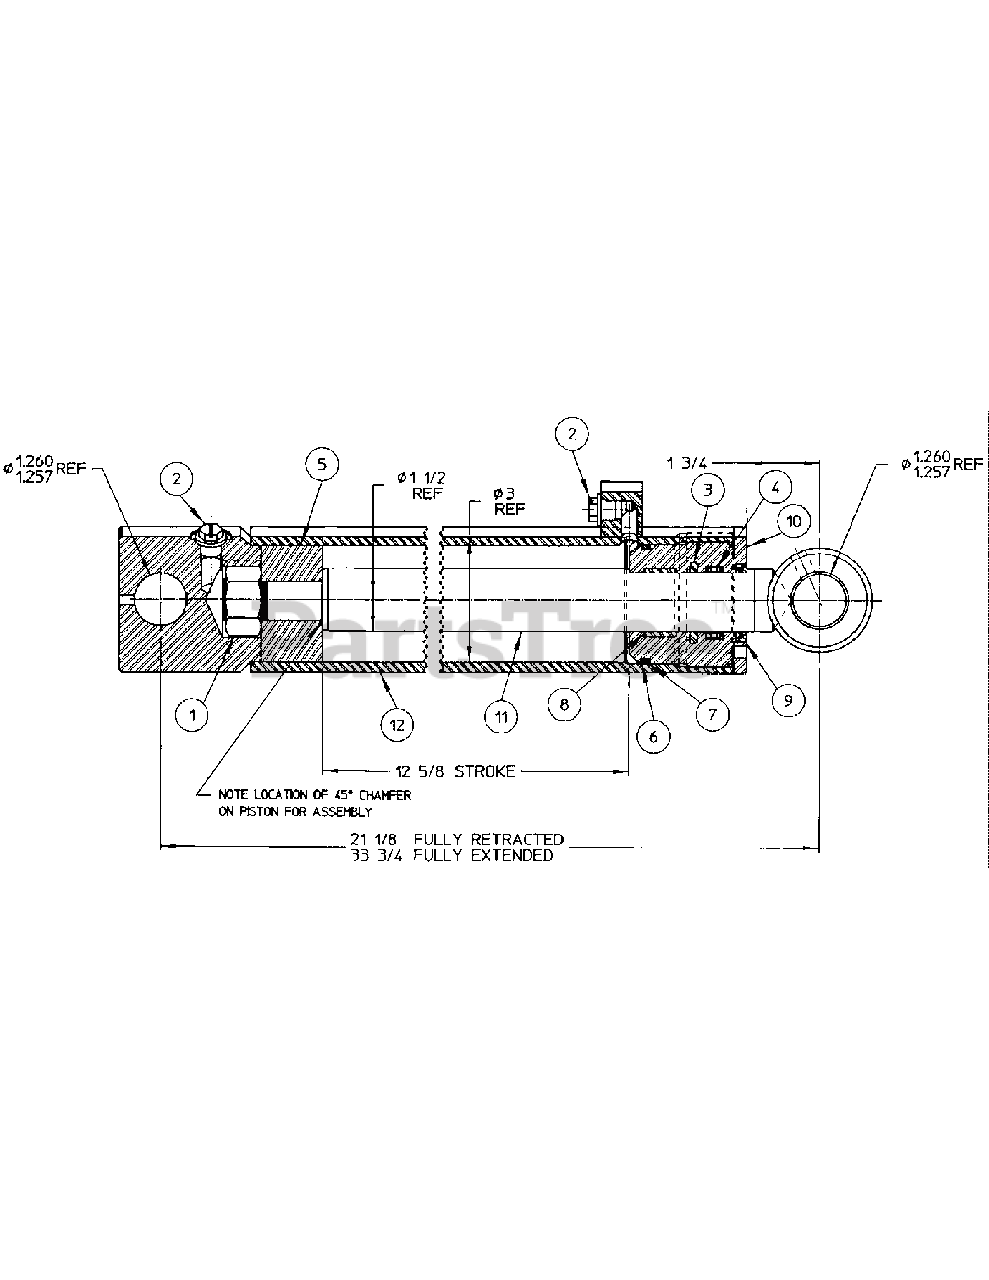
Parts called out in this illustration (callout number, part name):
1	NUT, 1'' NF LOCK
2	PLUG
3	STEP SEAL
4	ROD SEAL
6	O-RING, 3''OD X 2-3/4'' ID
7	BACK-UP RING
8	WEAR RING
9	ROD WIPER
10	GLAND WITH O-RINGS, BACK-UP, ETC
11	PISTON ROD WELDMENT
12	CYLINDER TUBE WELDMENT
